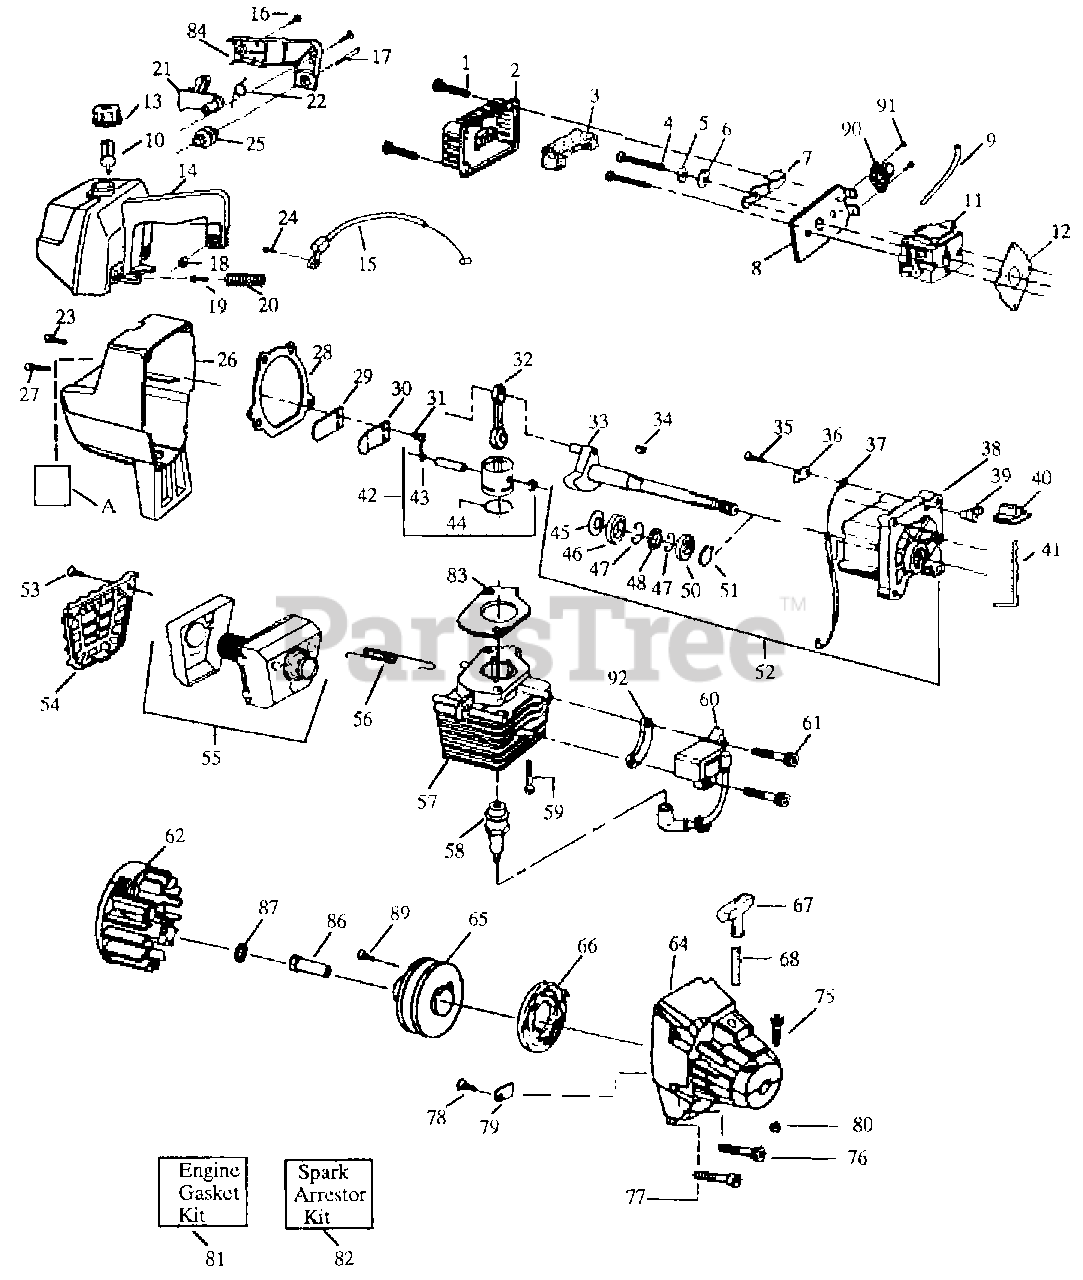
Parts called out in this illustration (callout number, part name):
2	Air Filter Cover
3	Air Filter
6	Wave Washer
7	Choke Shutter
8	Air Filter Plate Type I
8	Air Filter Plate Type II
9	Fuel Line Kit Fuel line
9	Fuel Line Kit Return line
10	Fuel Pick-up Ass'y.
11	Carburetor Type I - (WA207/207A)
11	Carburetor Type II - (WA219)
12	Carburetor Gasket
13	Fuel Cap Ass'y.
14	Handle & Tank Ass'y. Type I
14	Handle & Tank Ass'y. Type II
15	Throtte Cable Ass'y. Type I
15	Throtte Cable Ass'y. Type II
16	Screw
17	Shoulder Bolt
20	Rear Isolator Spring
21	Throttle Trigger
22	Throttle Spring
23	Screw
25	Isolator
30	Reed Stop
32	Connecting Rod Ass'y.
33	Crankshaft Ass'y.
34	Flywheel Key
36	Switch Insulator
37	Lead Wire
38	Crankcase Ass'y.
39	Switch Ramp
40	Switch Button
41	Switch Spring
42	Piston Kit
43	Piston Pin Retainer
44	Piston Ring
46	Inner Bearing
47	Retaining Ring
48	Crankshaft Seal
50	Outer Bearing
51	Retaining Ring
52	Crankcase & Crankshaft Ass'y,
54	Muffler Guard
55	Muffler Kit
56	Muffler Spring
57	Cylinder
58	Spark Plug
60	Ignition Module Kit
62	Flywheel Ass'y.
64	Fan Housing
65	Starter Pulley
66	Starter Spring
67	Starter Handle
68	Rope Kit
79	Pulley Retainer
81	Engine Gasket Kit
82	Spark Arrestor Kit
83	Cylinder Gasket
84	Handle Cover
86	Drive Coupling
89	Screw
90	Bulb Ass'y. - Type I
91	Screw - Type II
A	Instruction Decal Type I
A	Instruction Decal Type II
